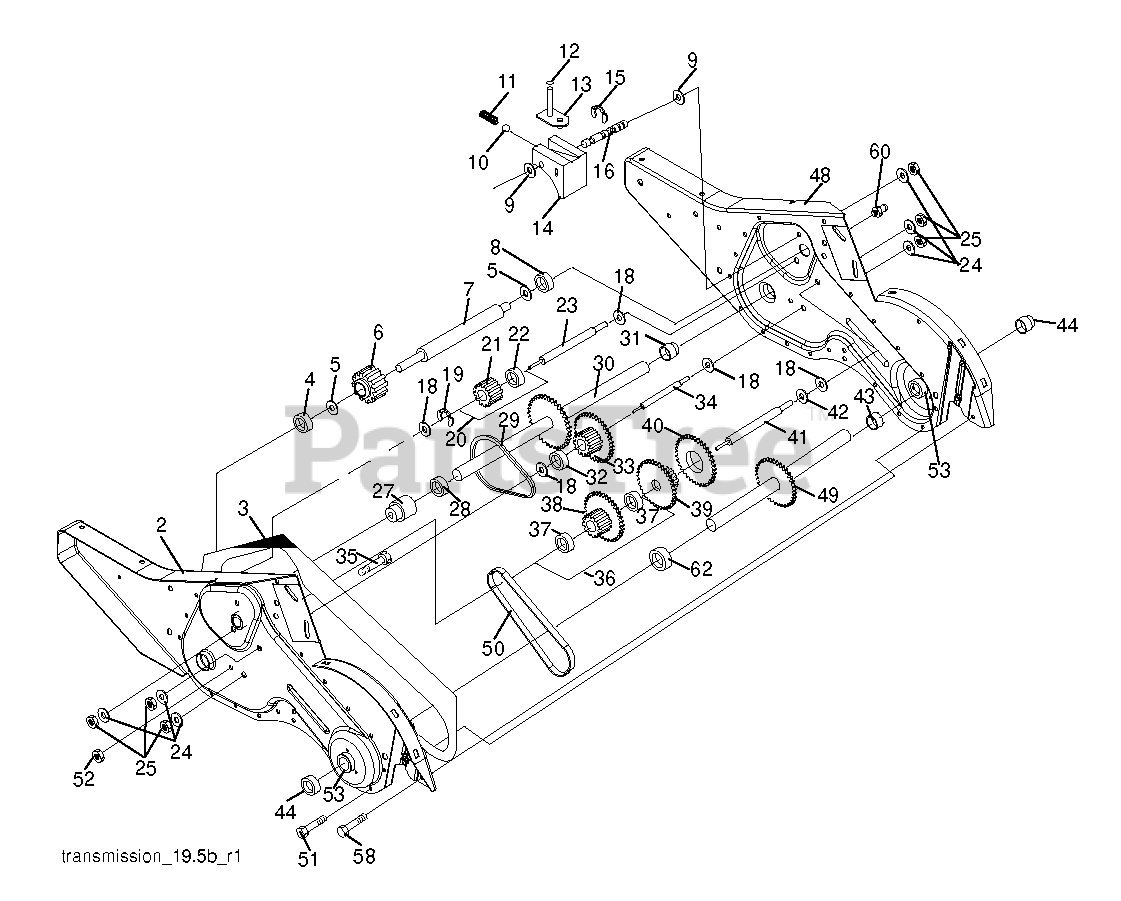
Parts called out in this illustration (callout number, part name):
2	GEARCASE.ASM.CRT.LH.W
3	GASKET.GEARCASE.CRT/DRT.TILLER
4	NEEDLE BRNG LT
5	THRUST WASHER
6	GEAR.PINION.INPUT
7	SHAFT.INPUT."D"".TILLER
9	WASHER, SEAL
11	SPRING-SHIFT CRT
12	O-RING TI
13	SHIFTING ARM
14	SHIFT FORK TI
15	KLIP RING
16	SHAFT.SHIFTER.TILLER
19	KLIP RING
20	GEAR ASSY CRT
21	GEAR-REV IDLR CRT
22	NEEDLE BEARING TI
23	SHAFT CRT
24	LOCKWASHER
25	NUT.ASF.HEX.7/16
27	BEARING.GROUND.DRIVE
29	CHAIN CRT
30	GROUND SHAFT ASS'Y
31	BEARING, SHAFT RH CRT
32	SPACER TI
33	SPRCKT 8 GEAR CRT
34	SHAFT.SECONDARY.REDUCTION.CRT
35	SCRW WHIZ LOK CRT
36	SPROCKET.ASM.W/BEARING.TILLER
39	GEAR TI
41	SHAFT.REDUCTION.TILLER
42	BRNG RACE T
43	SPACER TI
44	SEAL ASM, OIL
48	GEARCASE.ASM.CRT.RH.W/BEARING
49	SHAFT.ASM.TINE
50	CHAIN.TILLER
51	SCREW
53	BEARING KIT
58	BOLT SHOULDER 1/4-20 UNC X.875
60	FITTING.GREASE.TAPERED
62	SPACER.1.015X1.50X.650
